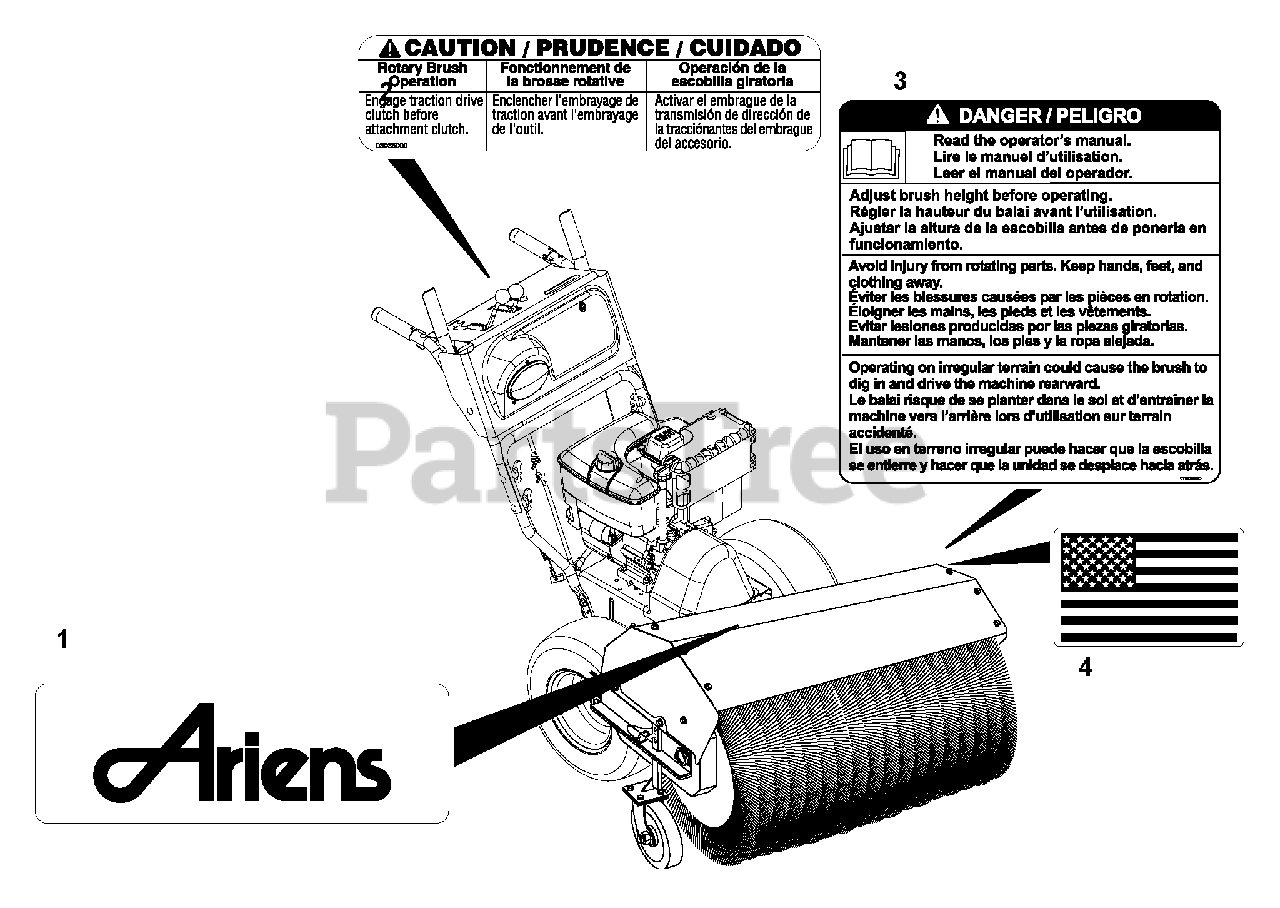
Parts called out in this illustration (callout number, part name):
1	DECAL - ARIENS
2	DECAL, CAUTION - BRUSH
3	DECAL, DANGER - POWER BRUSH
4	DECAL, AMERICAN FLAG
